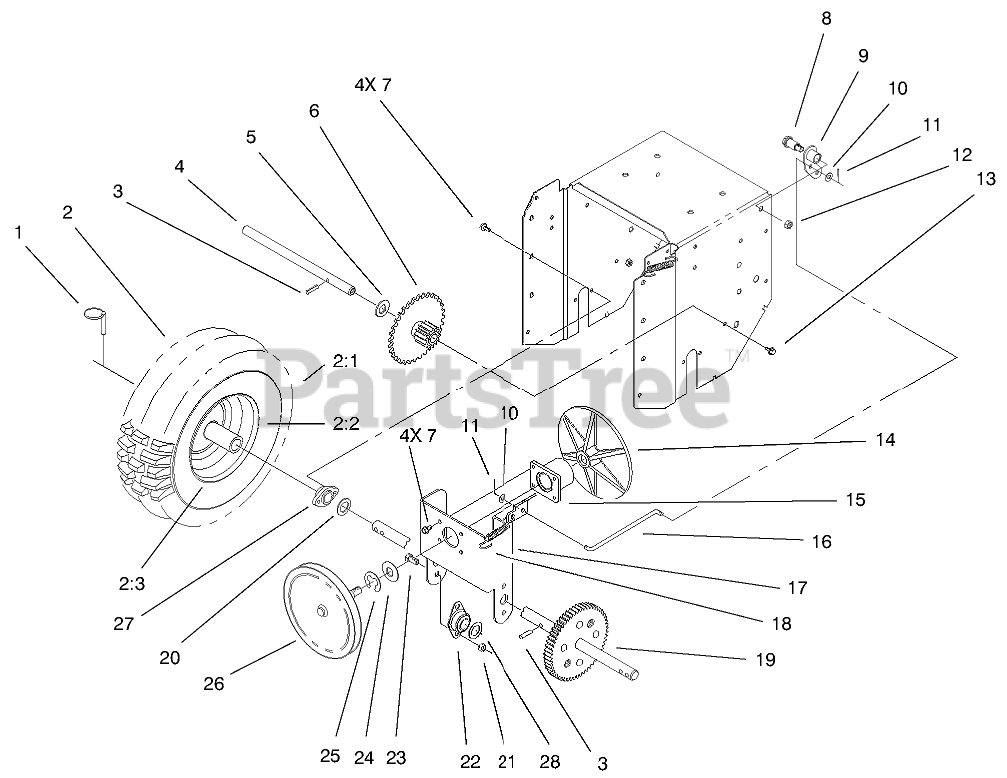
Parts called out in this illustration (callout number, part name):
1	PIN-LYNCH
2	WHEEL AND TIRE ASM
2:2	TUBE-INNER
2:3	RIM-WHEEL
3	PIN-ROLL, SLOTTED
4	SHAFT-INTERMEDIATE
5	WASHER
6	GEAR/BUSHING ASM
7	SCREW-HWH
8	BOLT-SHOULDER
9	HUB-PIVOT
10	WASHER-FLAT
11	PIN-COTTER
12	NUT-LOCK, NI
13	SCREW-HWHTF
14	DISC-FRICTION
15	BEARING HUB ASM
16	ROD-ENGAGE
17	FRAME-FRICTION PLATE
18	SPRING-ENGAGE
20	WASHER-THRUST
21	Nut-Lock Ni (only on: 38066)
22	BUSHING
23	SCREW-HH
24	WASHER-THRUST
25	RING-RETAINING, EXT
26	PULLEY/SHAFT ASM
27	BEARING-AXLE
28	WASHER-THRUST
